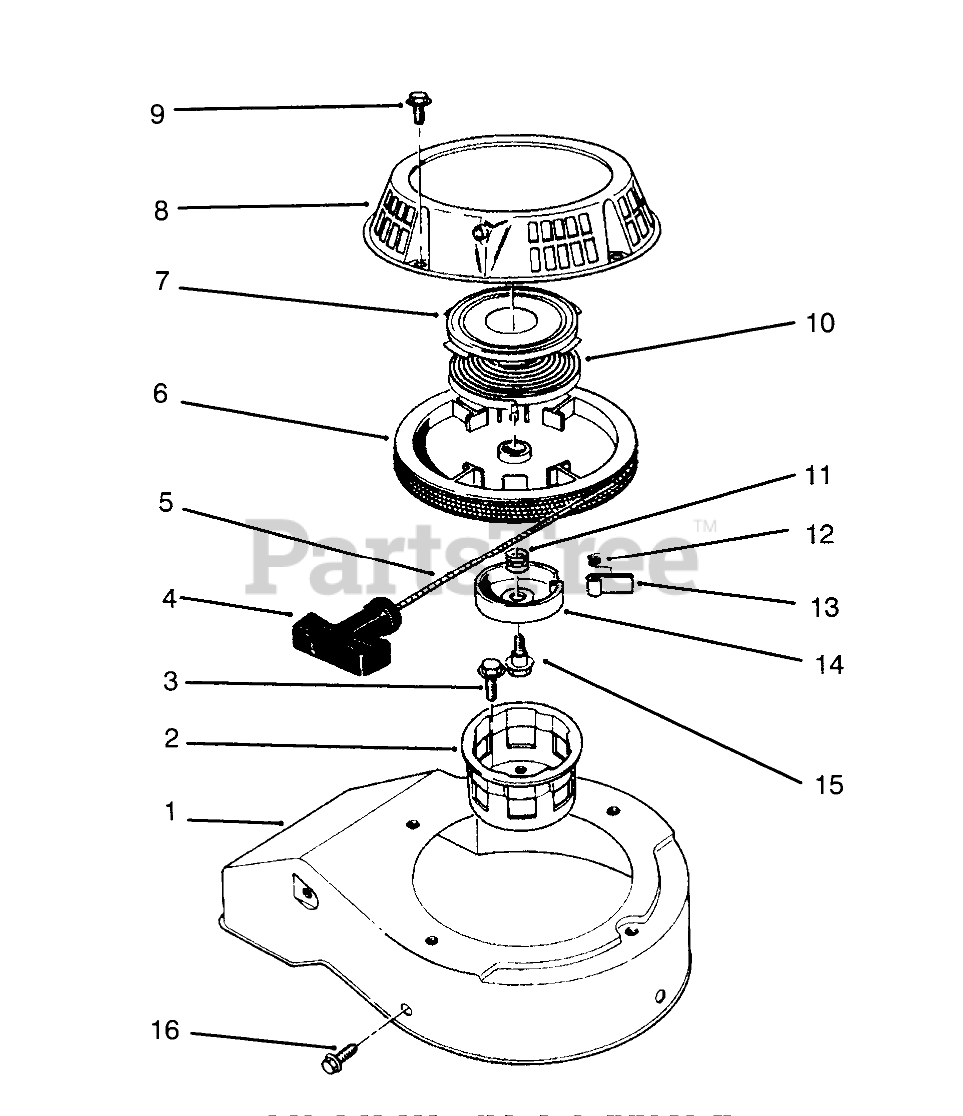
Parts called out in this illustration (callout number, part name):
1	Cover-Cooling Fan
2	PULLEY-CUP, STARTER
4	HANDLE-RECOIL
5	ROPE-STARTER
7	Retainer-Spring, Recoil
8	CASE-STARTER
9	SCREW-HHF
10	Spring-Recoil
11	SPRING
12	SPRING
14	RETAINER
